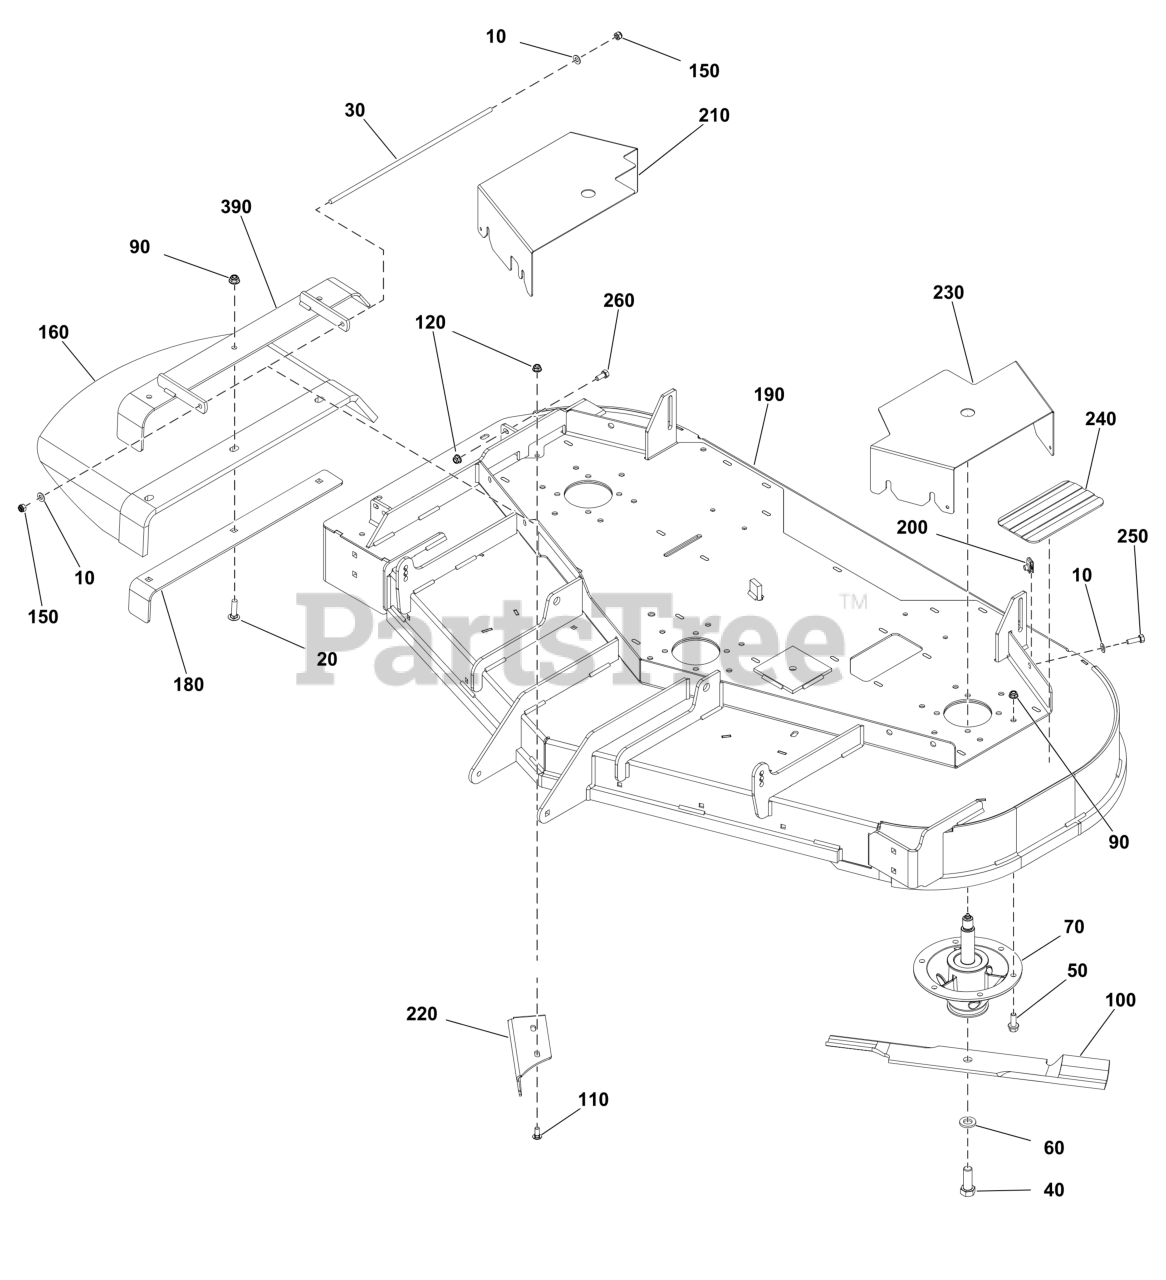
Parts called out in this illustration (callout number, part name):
10	WASHER
20	BOLT, 3/8-16 X 1-1/2
30	ROD
40	BOLT
50	BOLT
60	WASHER, 5/8" YZ
70	ASSEMBLY-SPINDLE
90	NUT, 3/8-16 HEX NYLOCK
100	BLADE SET, 61 DECK (3)
110	BOLT, 5/16-18 X 3/4",
120	NUT
150	NUT, 5/16-24 HEX NYLO
160	CHUTE, RUBBER DISCHARGE (5104442)
180	PLATE, SUPPORT
190	DECK SHELL W/DECALS, 60" (5422802B)
190	DECK SHELL W/ DECALS, 60" (5422802B) EXPORT
200	BODY CLIP, 5/16-18 X
210	GUARD, RH
220	DEFLECTOR
230	GUARD, LH
240	SAFETY WALK
260	BOLT, 5/16-18 X 3/4"
390	FRAME, Chute
